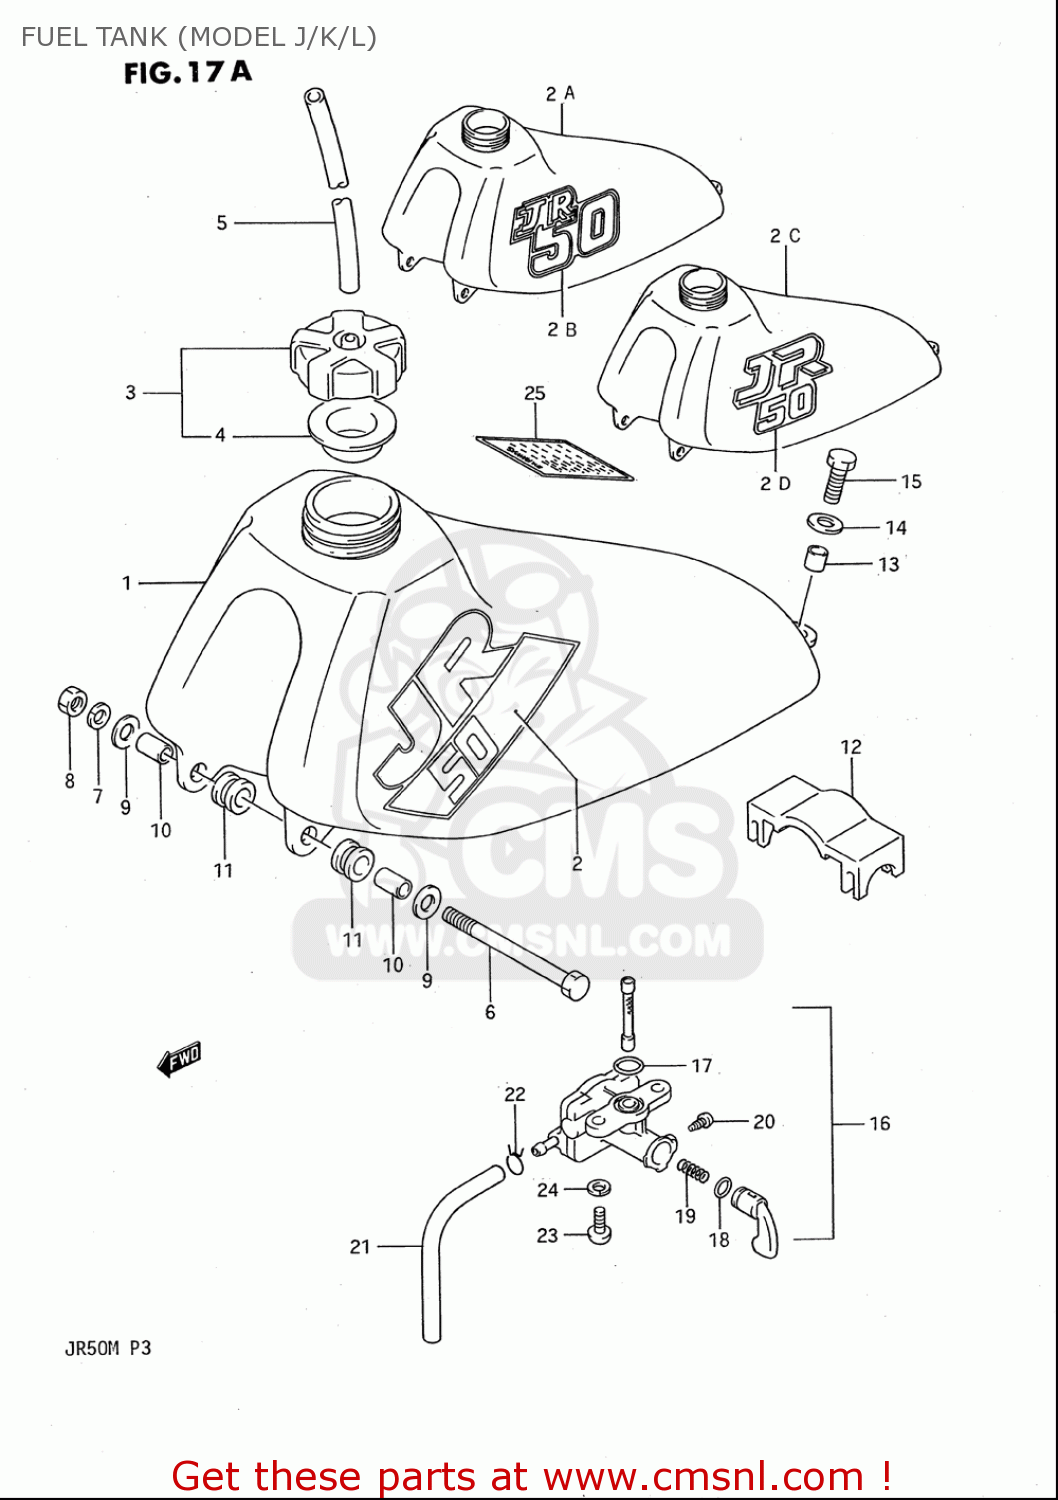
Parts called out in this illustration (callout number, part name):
1	TANK,FUEL
2A	TANK,FUEL
2B	TAPE,FUEL TANK
2C	TANK,FUEL
3	CAP SET,FUEL TANK
4	GASKET (NAS)
5	HOSE(5X8.2X600)
6	BOLT
7	WASHER,LOCK
8	NUT
9	WASHER(6.5X18X1)
10	SPACER (6.8X10X11.5)
11	CUSHION
12	CUSHION,FUEL TANK UPR
13	SPACER(6.5X9X7.2)
14	WASHER(6.5X18X1)
15	BOLT
16	COCK ASSY,FUEL
17	O RING
18	O RING,LEVER
19	SPRING
20	SCREW
21	HOSE
22	CLIP
23	SCREW
24	WASHER,LOCK
25	LABEL,WARNING
